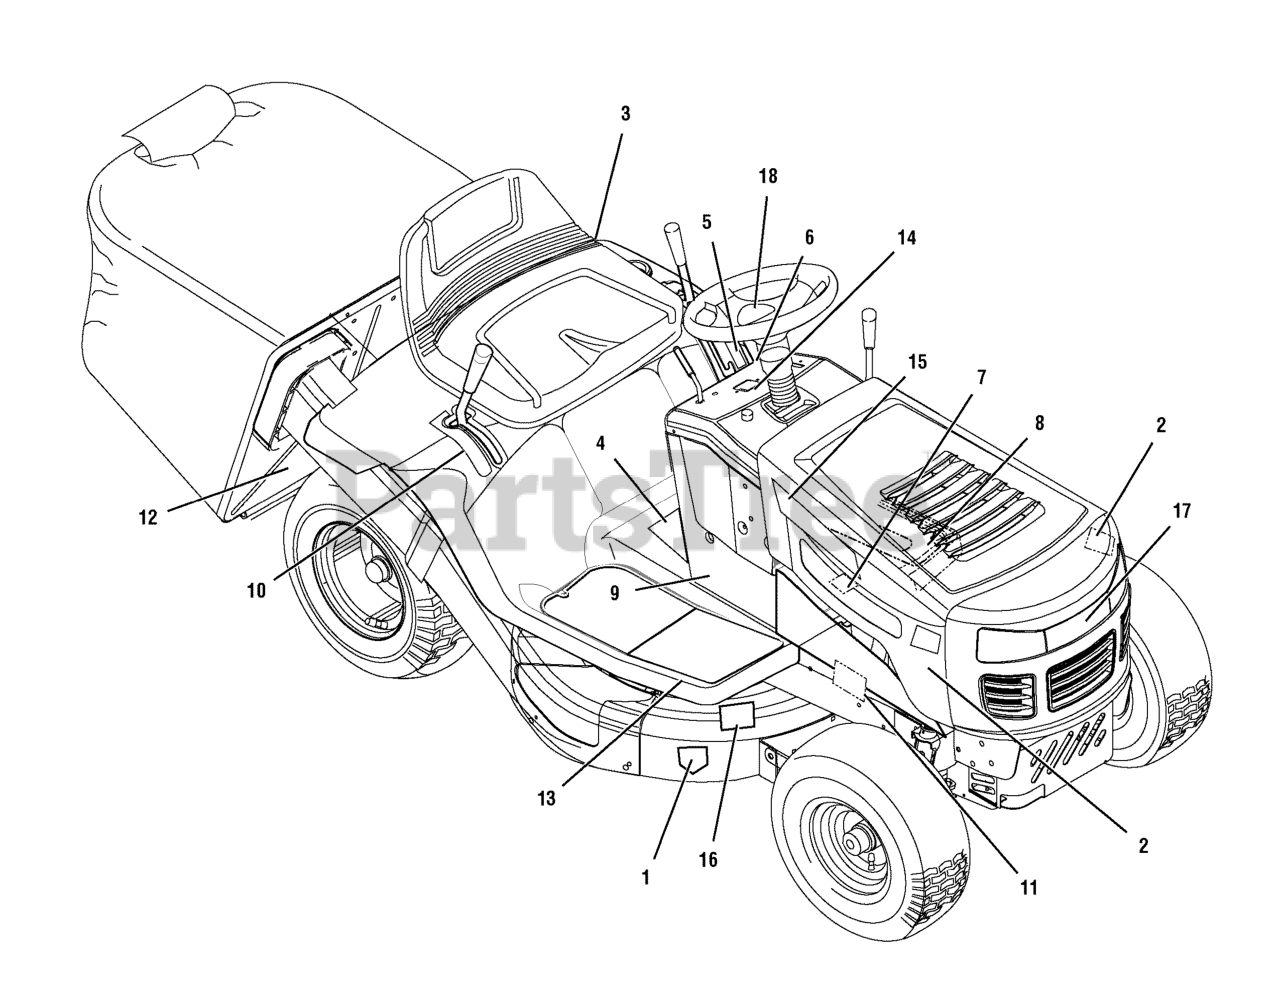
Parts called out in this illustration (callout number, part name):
1	DECAL, Cut Fingers Signal
2	DECAL, 145/76, Black, Red, White
3	DECAL, Gas
4	DECAL, Warning Export
5	DECAL, 7 Position Cut Height
6	DECAL, Deck Level
7	DECAL, DECK WIDTH 76cm
8	DECAL, Brake/Clutch Export
9	DECAL, B&S Logo
10	DECAL, 5 Speed
11	DECAL, Heat Shield Warning
12	DECAL, Warning Load Limit Export
13	DECAL, Warning Pinch Point
14	DECAL, Dash Symbols W1
15	DECAL, MURRAY
16	DECAL, 100db Export
17	DECAL, Front Hood
18	DECAL, Steering Wheel
